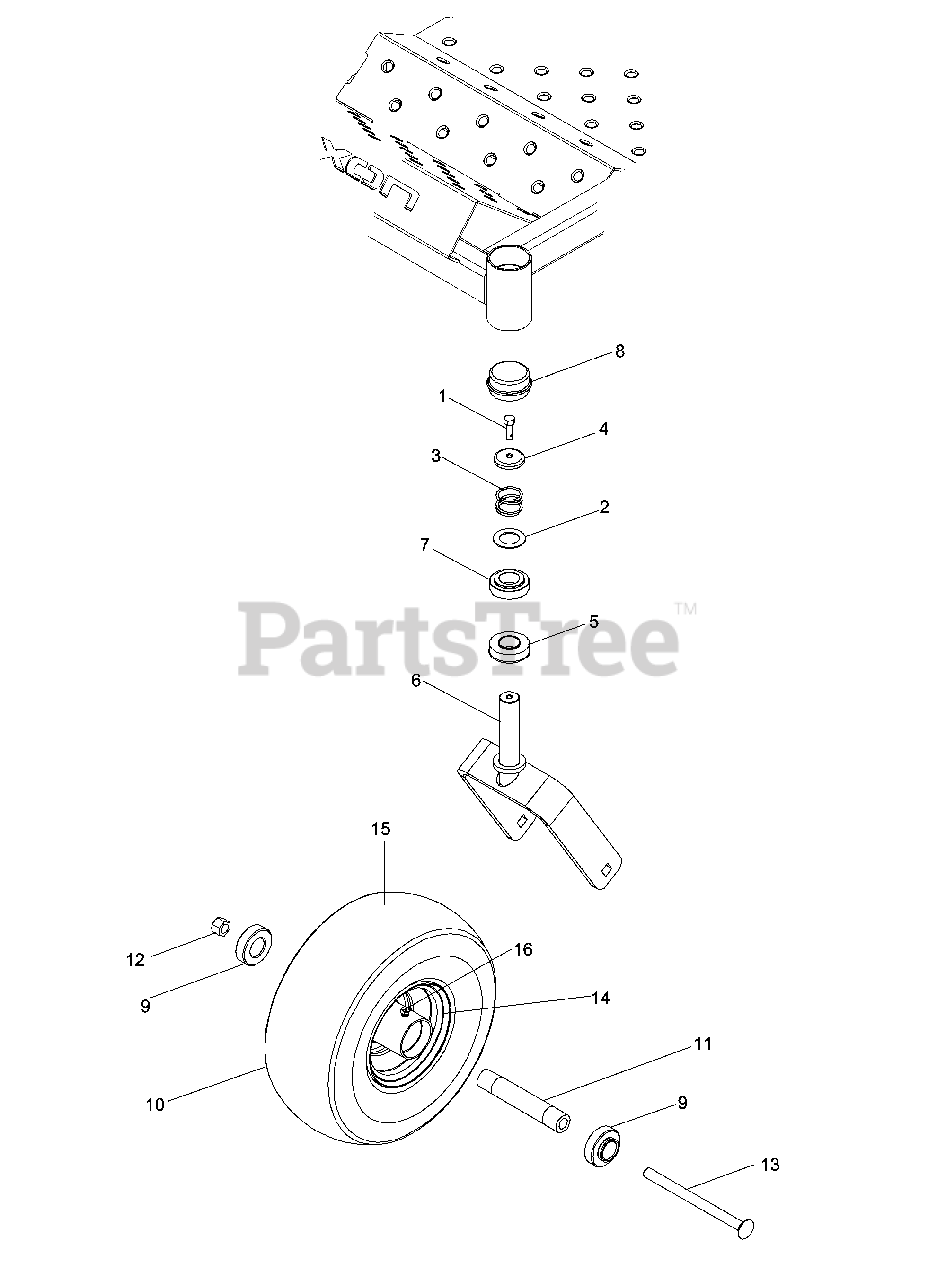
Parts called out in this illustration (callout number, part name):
1	5/16-18X1 HHB G5W/NY
2	WASHER, 1.025 ID X 1.64
3	SPRING, CASTER
4	CASTER.PLUG
5	BEARING
6	CASTER WLDT.
7	BUSHING, CASTER
8	GREASE CAP
9	BEARING-ECC LOCK
10	13-5 X 6 TIRE ASM.-SM
12	NUT, HEX 1/2-13 W/NYLOK
13	1/2-13 X 7 CARR. BOLT
14	WHEEL (REF.13985)
15	TIRE (REF.13985)
16	ZERK, 3/16, DRIVE IN
